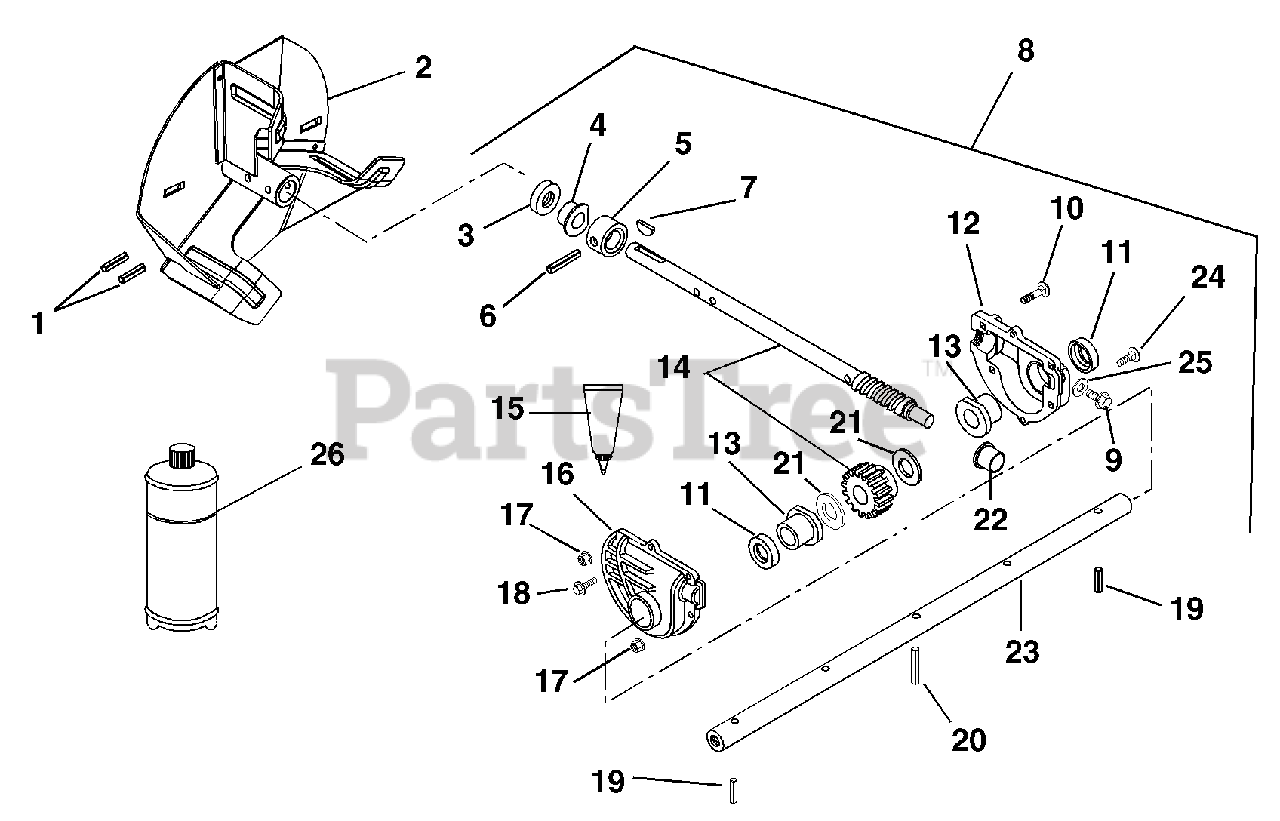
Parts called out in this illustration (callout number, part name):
1	PIN-ROLL .250X1.75
2	IMPELLER - .75 ID X 12" OD
3	SEAL-OIL .750X1.375X.250
4	BSHG-FLG .750X1.000X.750X1.250
5	THRUST COLLAR
6	PIN-GRV .188X1.25 TP A
7	KEY-WDRF .188X.875X.375 SAE11
8	CASE, GEAR-LARGE BORE-28"-ALUM
9	@SCR-TAP .38-16X.50 HWH TR YWZ
10	@BLT-RDHDSQNK .25-20X1.25 G5YZ
11	SEAL-OIL 1.000X1.375X.250
12	CASE, GEAR-LH-LARGE BORE-ALUM.
13	BSHG-FLG 1.00X1.12
14	WORM SHAFT & GEAR ASSY
15	LOCTITE GASKET 518--850CC CRTG
16	CASE, GEAR-RH-LARGE BORE-ALUM.
17	@NUT-SPNLK-FLG .25-20 YWZC
18	SCR-TAP 10-24X.75 HWH TR YWZC
19	PIN-ROLL .188X1.50
20	PIN-GRV .313X1.44 TP C
21	WSHR-HRD-THRS 1.007X1.542X.062
22	BSHG-FLG .502X1X.750
23	SHAFT, RAKE - 28"
24	@BLT-RDHDSQNK .25-20X1.00 G5YZ
25	WSHR-FIBER .437X.656X.032
26	ARIENS 16 OZ.BOTTLE OF L2 LUBE
